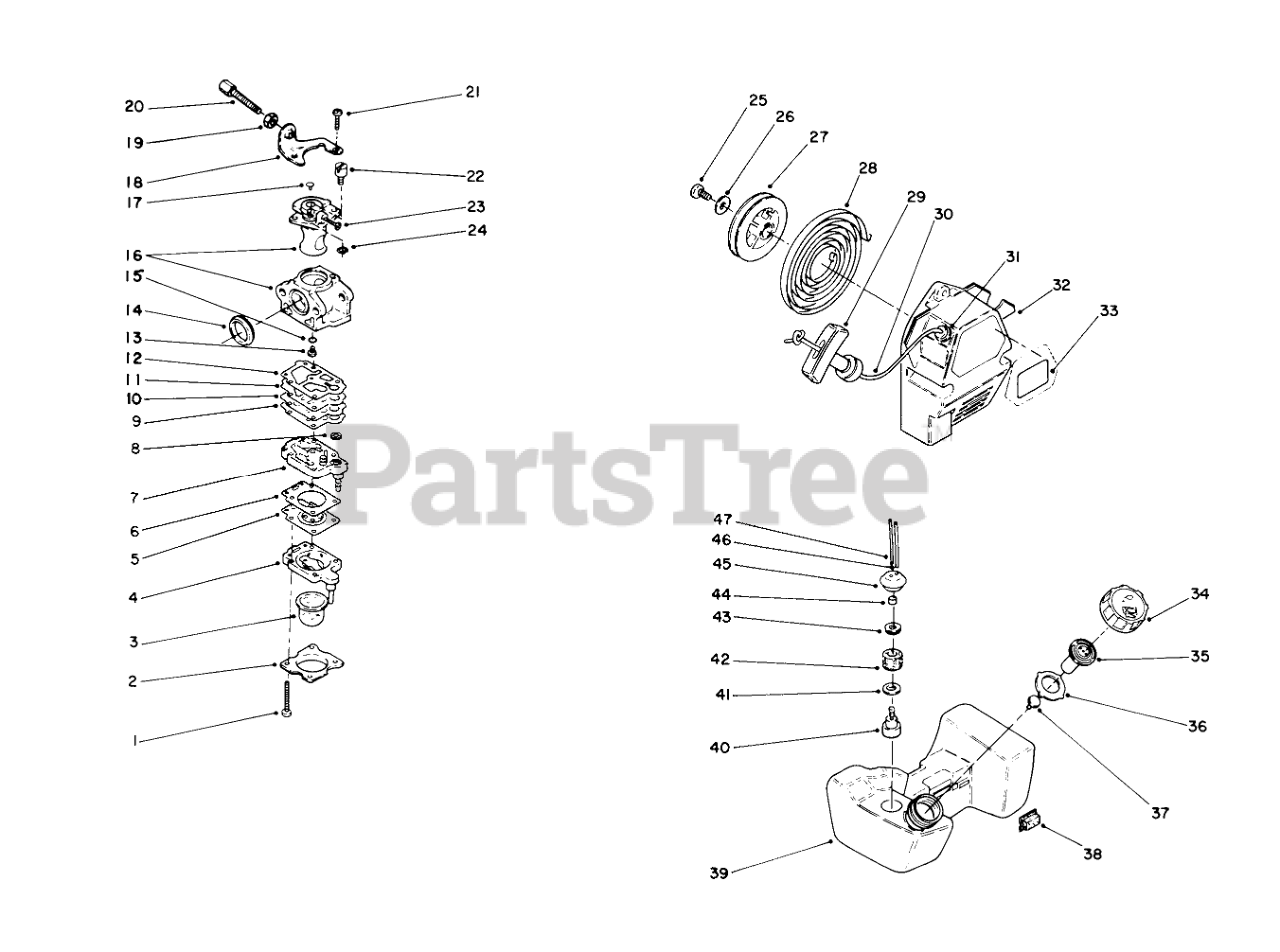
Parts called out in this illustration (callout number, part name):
1	SCREW
2	Cover-Primer
3	PRIMER PUMP
4	PRIMER BODY
5	DIAPHRAGM
6	DIAPHRAGM GASKET
7	PUMP BODY
8	SCREEN
9	PUMP GASKET
10	Plate
11	DIAPHRAGM
12	DIAPHRAM GASKET
13	MAIN JET
14	RUBBER CARB GASKET
15	MAIN JET O-RING
16	Body-Carburator-(Ref.)
18	BRACKET
19	LOCKNUT
20	ADJUSTING SCREW
21	SCREW
22	Holder-Wire
23	THROTTLE VALVE
25	SCREW
26	WASHER
28	SPRING
29	Knob-Starter
30	Rope-Recoil
31	GUIDE
32	Case-Starter
33	Decal-Toro
34	FUEL TANK CAP
35	BREATHER VALVE
36	PACKING
39	Tank Assembly-Fuel (Incl. Ref. #34-47)
40	Weight-Filter
42	Filter-Fuel
43	Washer-Seal
44	COLLAR
45	FUEL TANK GROMMET
46	TUBE, FUEL
47	RETURN FUEL HOSE
